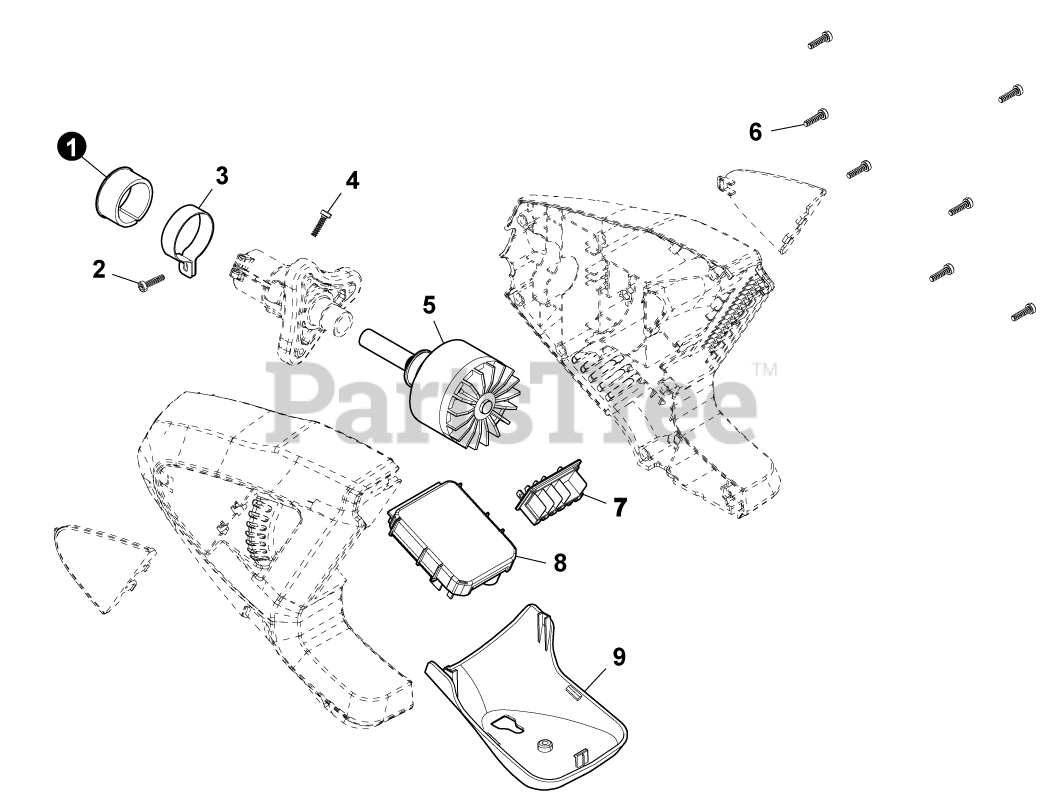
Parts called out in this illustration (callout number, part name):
2	SCREW
4	SCREW
6	SCREW
7	HOLDER, BATTERY
